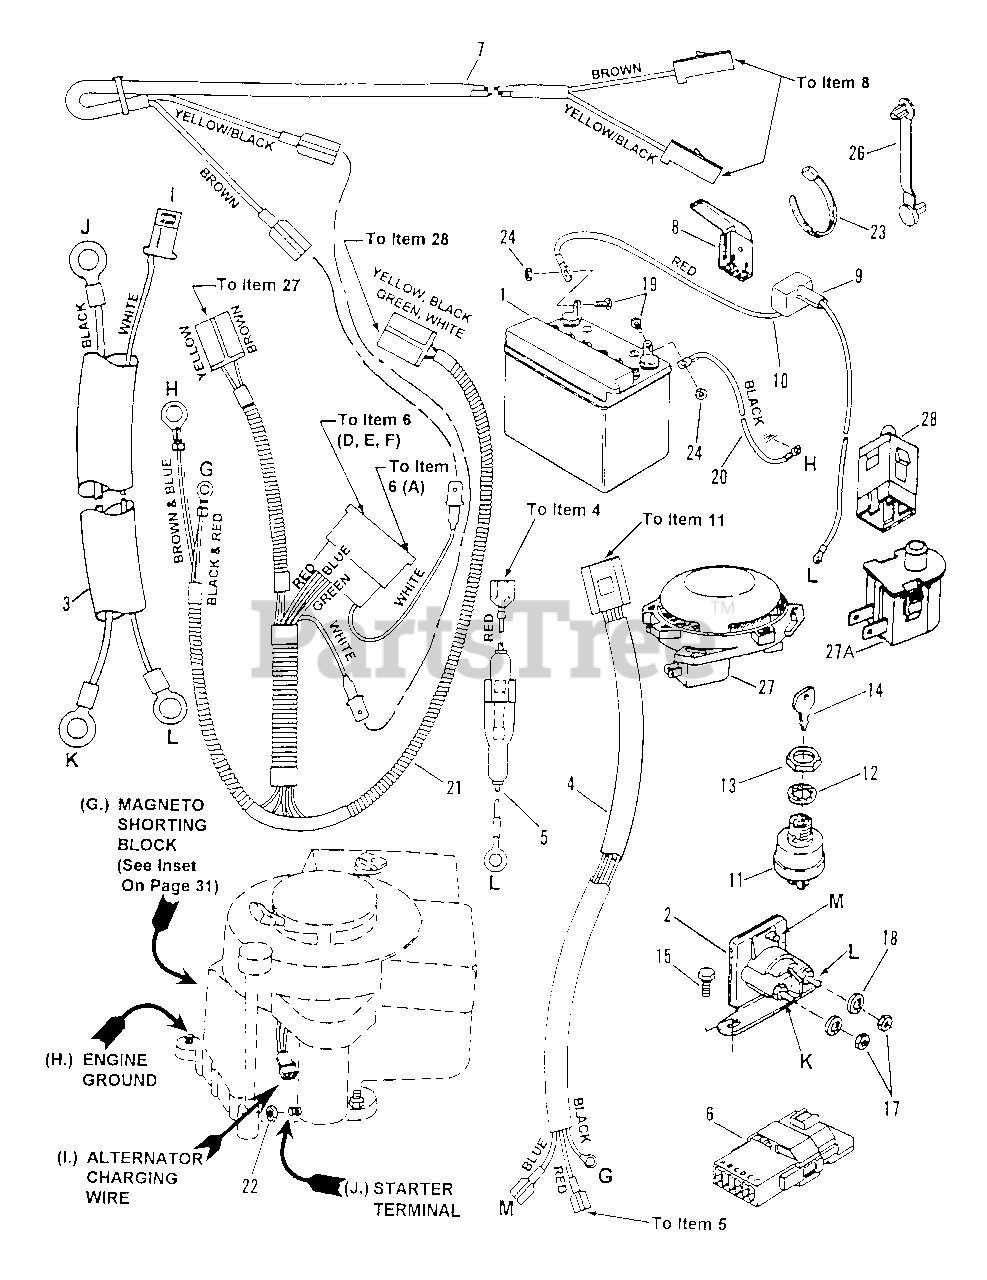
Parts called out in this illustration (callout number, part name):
1	KIT, 12Volt Dry Charge Battery
2	SOLENOID
3	HARNESS, Starter Wiring (Briggs Engines)
4	HARNESS, Ignition Wiring (Briggs Engines)
5	HOLDER, Fuse
6	INTERLOCK Module (Briggs)
7	HARNESS (Deck Interlock Wiring)
8	SWITCH, Deck Interlock
9	COVER, Battery Cable
10	CABLE, Positive (Red)
11	SWITCH, Ignition
12	WASHER, 5/8 Internal Tooth Lock
13	NUT, 5/8-32 Hex
14	KEY, Switch
15	SCREW, 1/4-20 x 1/2" Self-Tapping
17	NUT, 1/4-20 Hex
18	WASHER, 1/4 Internal Tooth Lock
19	SCREW, 1/4-20 x 5/8" Hex Head Cap
20	CABLE, Negative
21	HARNESS, Operator Presence Control (OPC) Wire
22	NUT, 1/4-20 Hex
23	TIE, 7" Long Cable
24	NUT, 1/4-20 Hex Lock
26	TIE, 2" Long Cable
27	SWITCH, Seat (8 HP & 10 HP Engines)
27A	SWITCH, Seat (13 HP Engines)
28	SWITCH, Operator Presence Control (OPC) Traction
